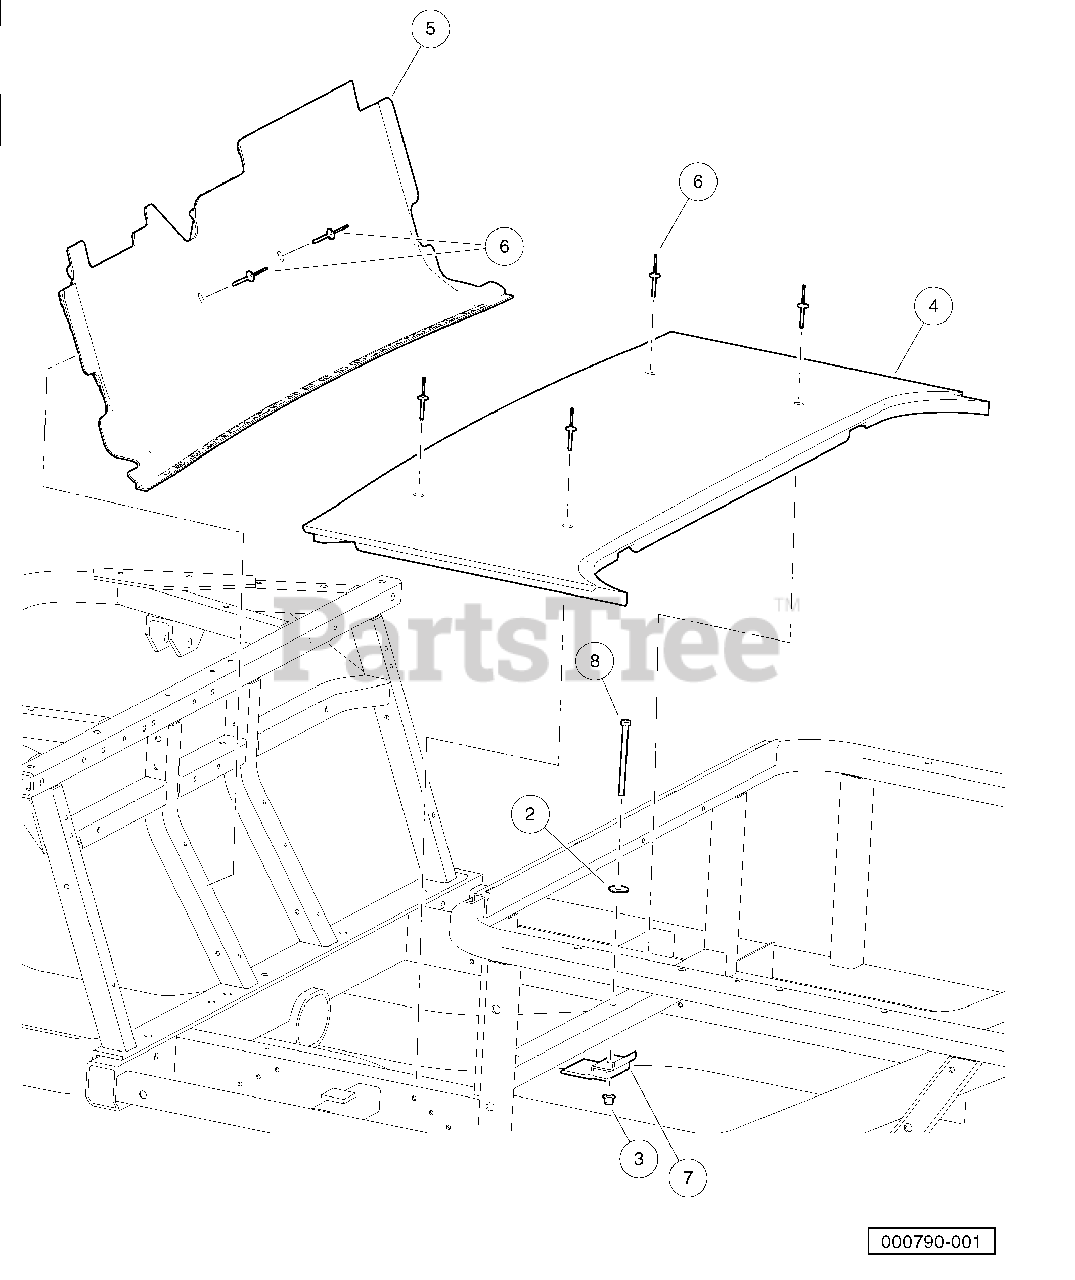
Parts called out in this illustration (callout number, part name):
1	Instl, Floorboard
2	Washer, 5/16 Type B Flat
3	Lock Nut, Flg M8 X 1.25 Nylon
4	Floorboard, Lower
5	Floorboard, Upper
6	3/16 X 1.19 Alum Rivet, Blk
7	Bracket, Support, Floorboard
8	Bolt, M8 X 1.25 X 110
